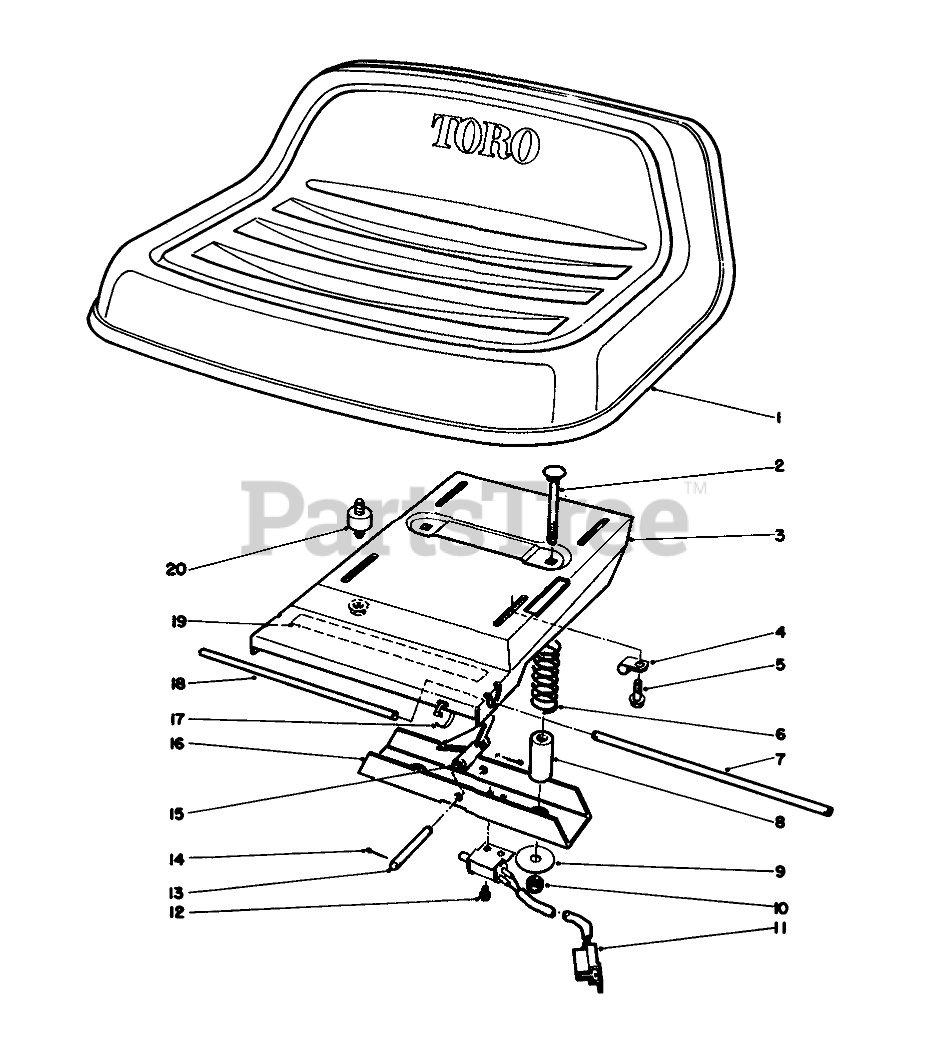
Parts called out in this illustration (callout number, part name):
2	BOLT-CARR
3	Base-Seat
4	CLAMP
5	NUT-HF
6	COMPRESSION SPRING
7	SEAT BASE ROD
8	SEAT SWITCH SPACER
9	WASHER-FLAT
10	NUT-LOCK, NI
11	INTERLOCK SWITCH
12	SCREW-TAPTITE
13	Pin-Clevis
14	Cotter Pin
15	LEVER SWITCH
16	CHANNEL-SEAT SWITCH
17	TIE-CABLE
18	TUBE-SEAT
19	DECAL
20	ISOLATER-SEAT
